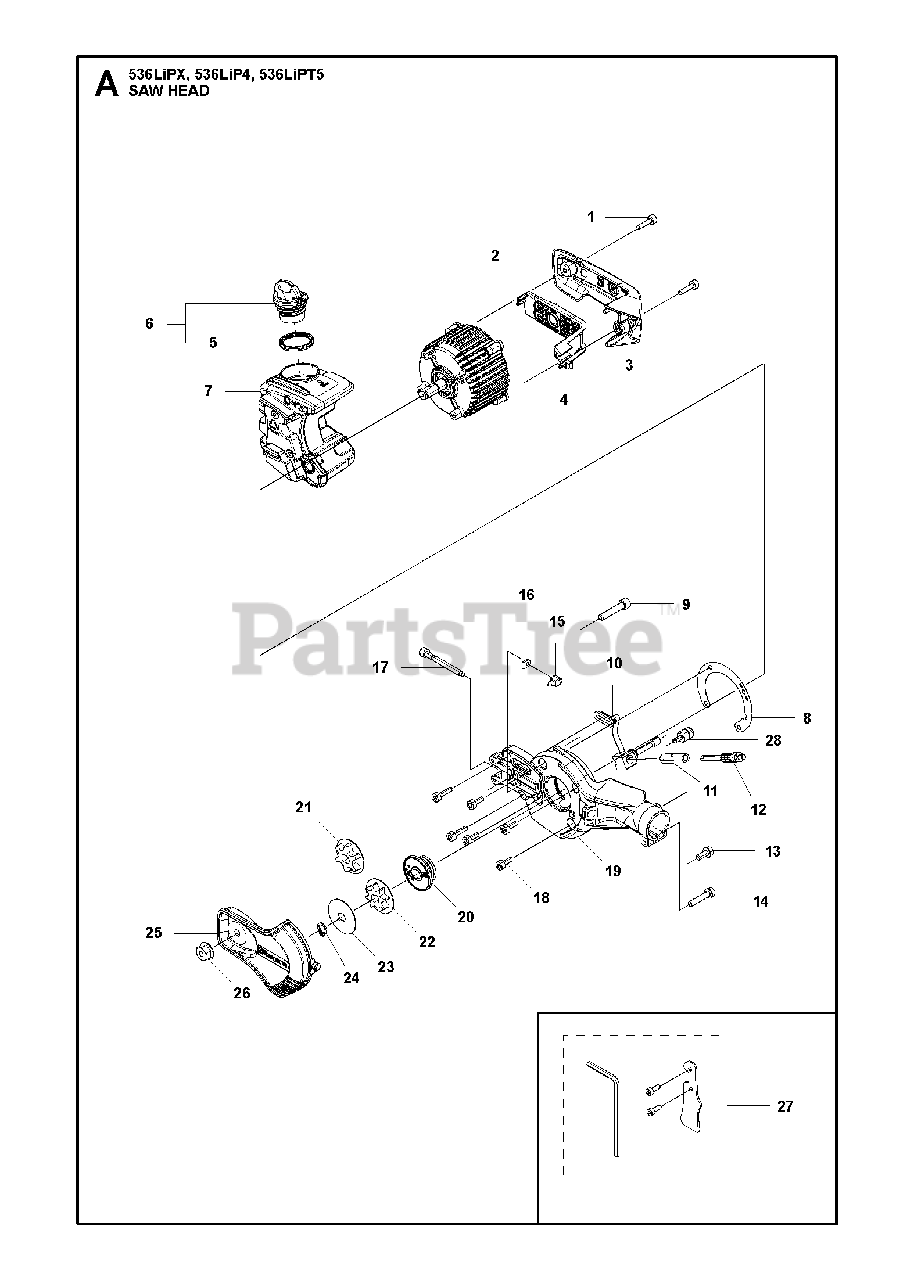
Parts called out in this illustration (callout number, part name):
1	SCREW
2	Motor Cover
3	Cable Bracket
4	MOTOR ASSY BLDC
5	Tank Cap Gasket
6	Tank Cap Assembly
7	Oil Tank Assembly
8	INSULATOR HEAT
9	SCREW IHSCM
10	OIL HOSE
11	PUMP CYLINDER
12	PISTON PUMP
17	Chain Tensioner Screw
19	CHASSIS ASSY
20	PUMP PINION ASSY
21	SPUR SPROCKET
22	SPUR SPROCKET 1/4" 8T
24	RETAINING RING SGA 10
25	COVER CHAIN ASSY HUSQVARNA
26	HEXAGON NUT FLANGED
27	ACCESSORY BAG HOOK
28	OIL PLUMMET
